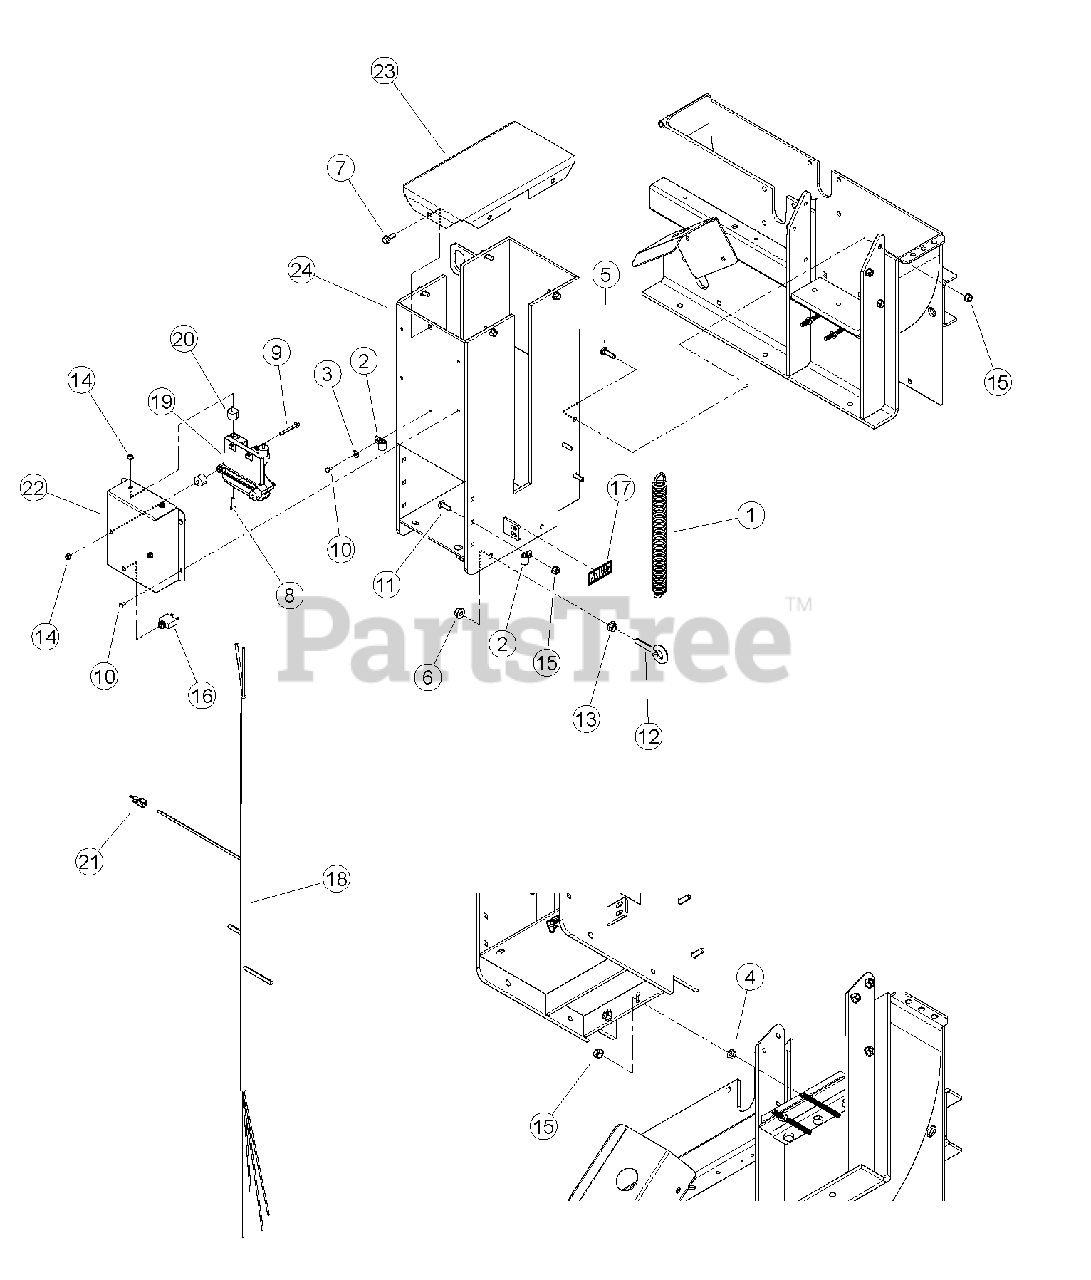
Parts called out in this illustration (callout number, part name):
1	SPRING, EXTENSION
2	CLAMP, 9/16 COATED
3	WASHER, 1/4" FLAT ZP
4	NUT, 3/8" SERRATED FLANGE NC ZP
5	BOLT, 3/8 X 1-1/2" GR5 CRG NC ZP
6	NUT, 1/2-13 NYLOCK FLANGE
7	BOLT, 3/8 X 1 FLANGE NC
8	BOLT, 1/4 X 1-1/4 FLANGE NC
9	BOLT, 1/4 X 2-1/4 FLANGE NC
10	BOLT, 1/4 X 1/2 HCS G5 ZP
11	BOLT, 3/8 X 1-1/4" GR5 CRG NC ZP
12	EYEBOLT, 1/2 X 2" ZP
13	NUT, 1/2 SPIRAL LOCK NC ZP
14	NUT, 1/4-20 NYLOCK-FLANGE
15	NUT, 3/8-16 NYLOCK FLANGE
16	CIRCUIT BREAKER, 10 AMP RESETTABLE
17	DECAL, CRUSHING ISO
18	HARNESS, 9" PTO PLUS 1 CONTROLLER
19	CONTROLLER, PLUS 1 CHIPPER
20	BUMPER, 1" OD W/ 1/4" STUD
21	PLUG, JUMPER HARNESS
22	ENCLOSURE, PLUS 1 MOUNT
23	WELDMENT, TOP ROLLER COVER
24	WELDMENT, ROLLER SUPPORT
